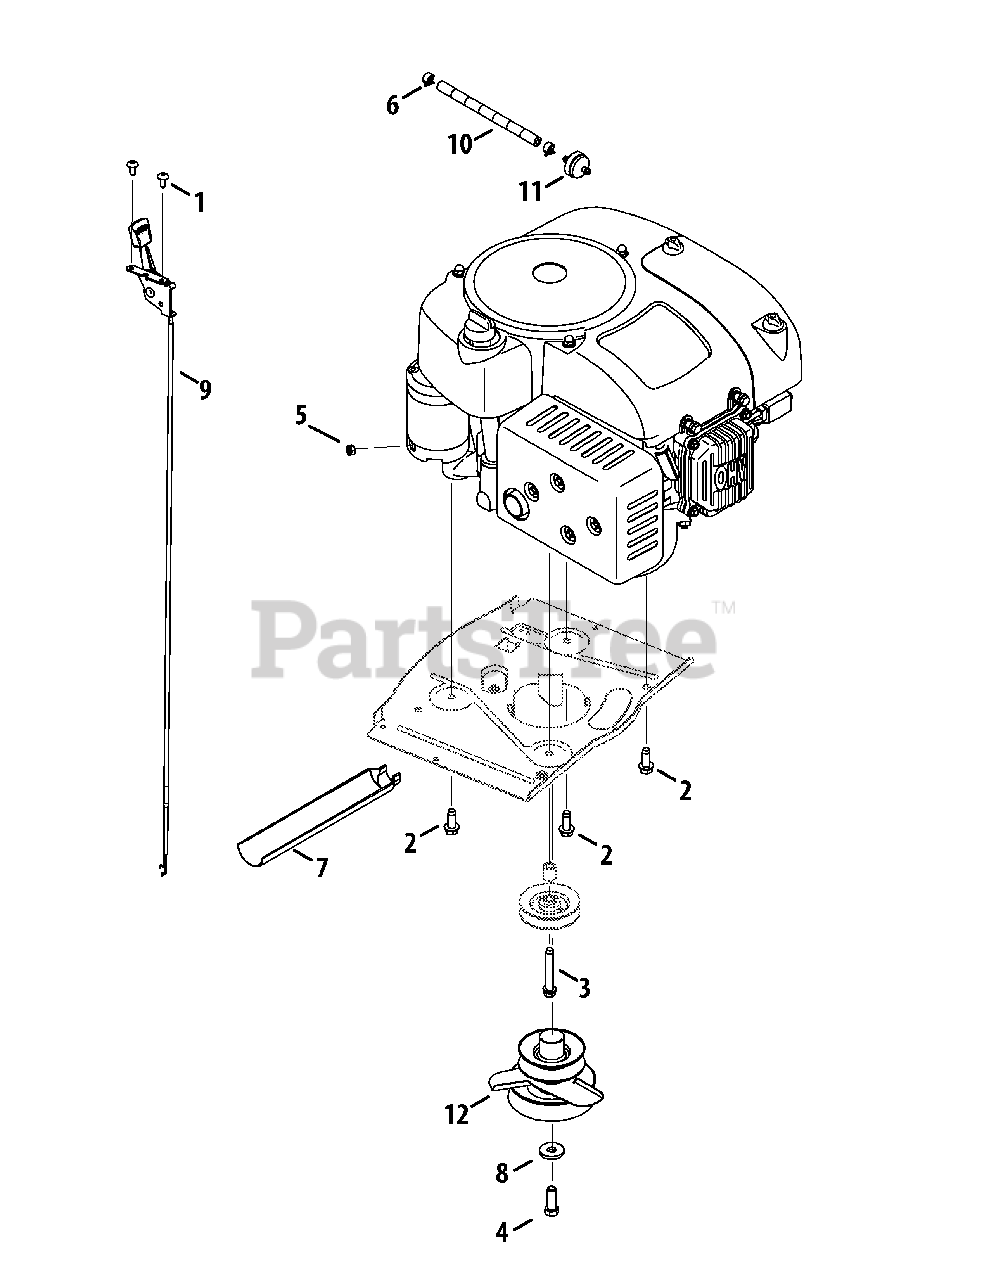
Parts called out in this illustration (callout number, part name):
1	Tap Screw, 1/4-20, 0.500
2	Tap Screw, 3/8-16, 1.000
3	Tap Screw, 3/8-16, 2.250
4	Hex Head Screw, 7/16-20 x 1.25
5	Nut, Hex Nylon Lock, M6-1.0
6	Hose Clamp, .490 DIA.
7	Oil Drain Sleeve
8	Flat Washer, .450 x 1.25 x .164
9	Throttle/Choke Cable 31 Lg.
10	Low Permeation Fuel Line, 1/4
11	Fuel Filter, 1/4", 298090
12	Engine Pulley, 4.46 / 3.39
